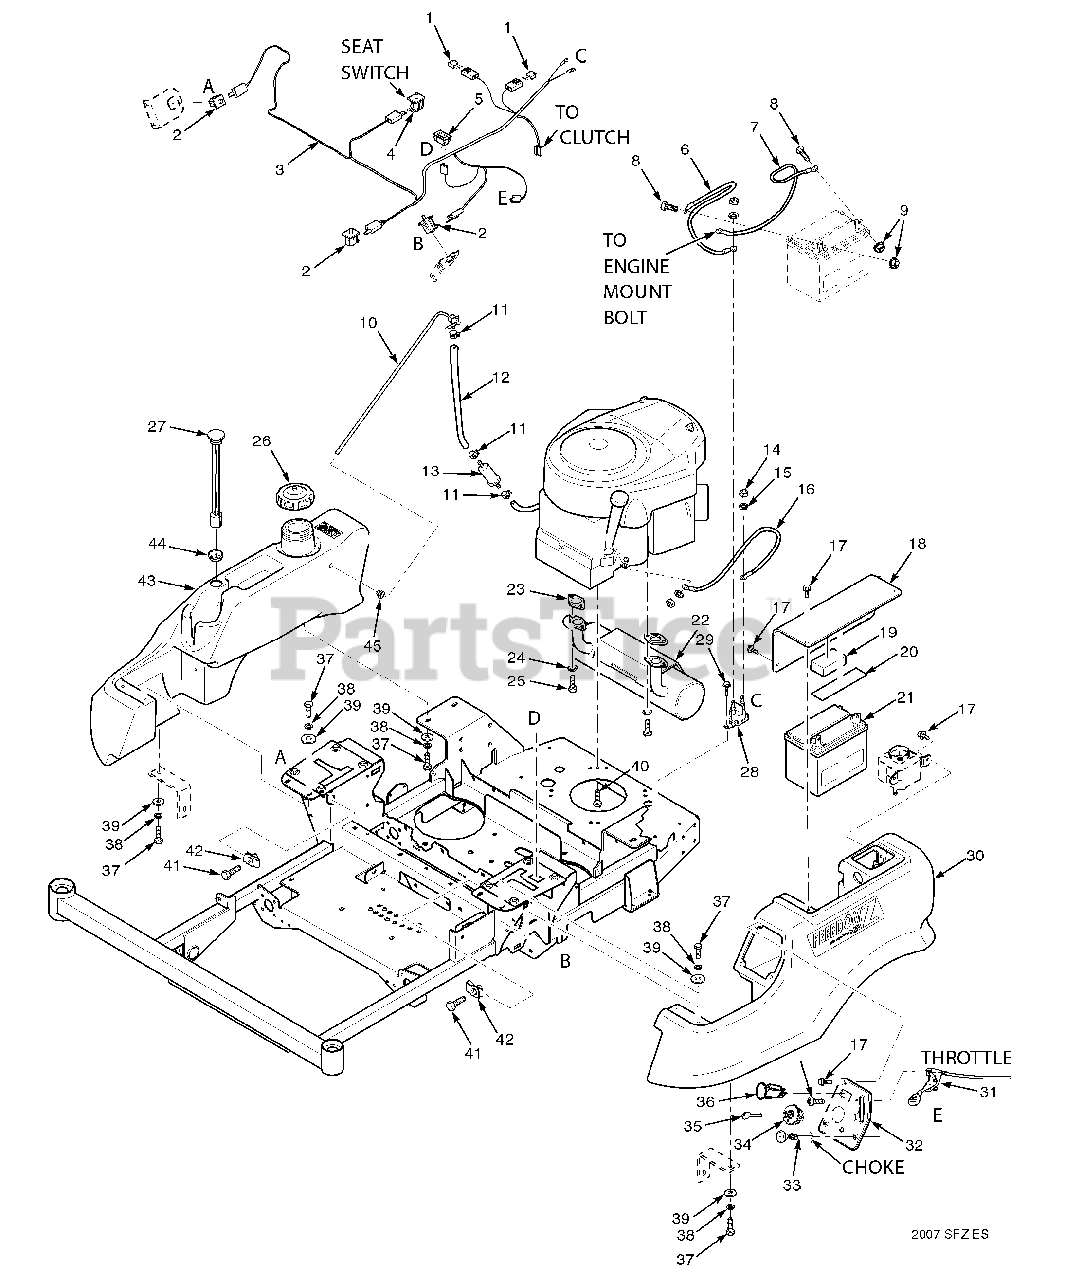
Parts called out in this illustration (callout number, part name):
1	Fuse, 20amp
2	Switch
3	Wire Harness, Main
4	Switch, Seat
5	Hourmeter
6	Battery Cable, Red 25"
7	Battery Cable, Black 27"
8	Bolt, Hex Head 1/4-20 x 1/2"
9	Nut, 1/4-20
10	Fuel Tube Assy.
11	Clamp, Fuel Hose 1/4"ID
12	Fuel Hose
13	Fuel Filter
14	Nut, 5/16-24 UNF Jam
16	Battery Cable, Red 9"
17	Bolt, Hex Head 1/4-20 x 1/2" Serrated Flange
18	Battery Cover
19	Pad, Battery Hold Down
20	Rubber Pad
21	Battery
22	Muffler, Briggs & Stratton
23	Exhaust Gasket
24	Lockwasher
25	Bolt
26	Cap, Fuel Tank
27	Fuel Gauge Assy.
28	Solenoid
29	Bolt, Self Tapping 1/4-20 x 3/4" Shakeproof
30	Tank, LH
31	Throttle Cable
32	Instrument Panel w/Decal
33	Choke Cable
34	Ignition Switch
35	Key, Ignition
36	PTO Switch
37	Bolt, Hex Head 5/16-18 x 3/4"
38	Lockwasher, 5/16" Spring
39	Flatwasher, 5/16-.375 x .875 x .083
40	Bolt, Hex Head 5/16-18 x 1-1/2"
41	Bolt, Hex Head 3/8-16 x 1-1/4" Special Lock
42	U-Nut, 3/8-16
43	Fuel Tank Assy, RH
44	Grommet
45	Bushing, .56" Dia. Viton
